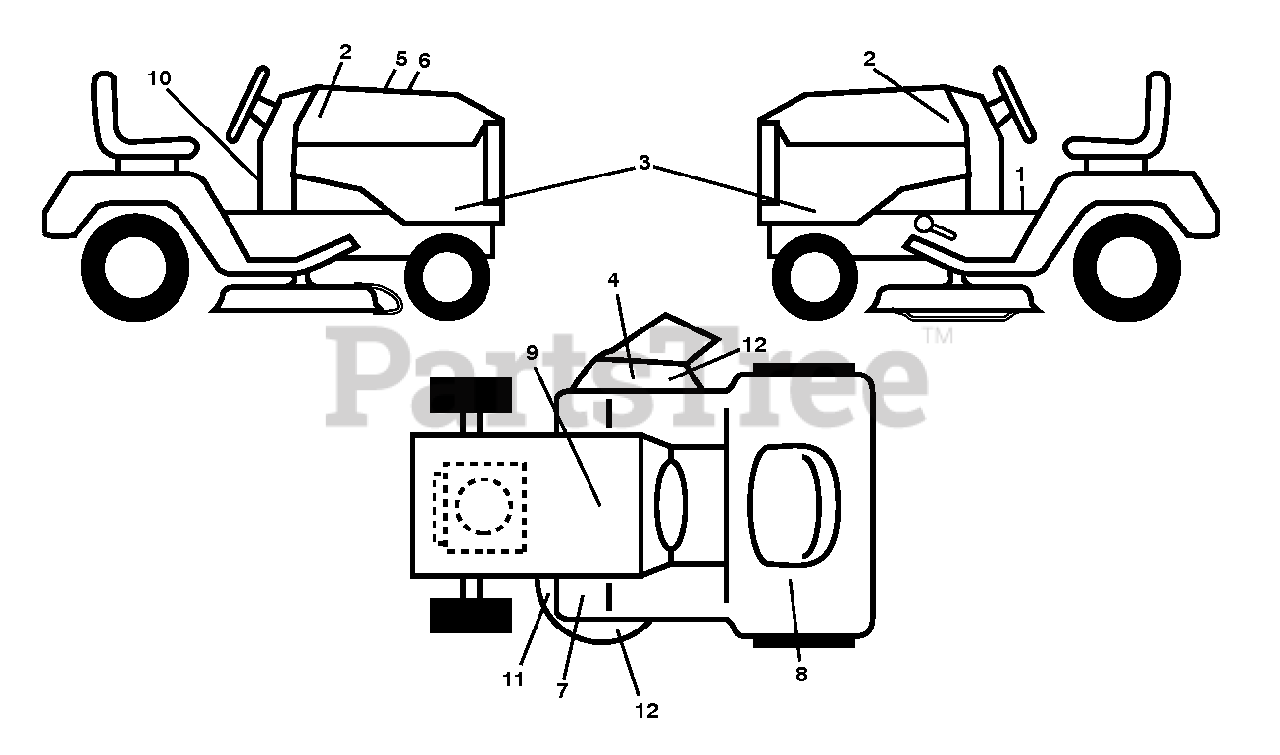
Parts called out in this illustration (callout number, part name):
1	DECAL.FENDER.WARNING.ENG
2	RP.DECAL.BADGE.170MM.TEXTLOGO
3	DECAL.SDPNL.HUSQGT2.MS668.YTH2
4	DECAL, CAUTION
5	DECAL.WARNING.CUST.RESP.E85.
6	DECAL.REPLACEMENT.960480014
7	DECAL.PEDAL.HUSQ.CROWN
8	DECAL.WARN.RESERVE.FUEL
9	DECAL BTRY SYMBOLS
11	DECAL.MOWER.SCH.48/54
12	DECAL, NO STEP
